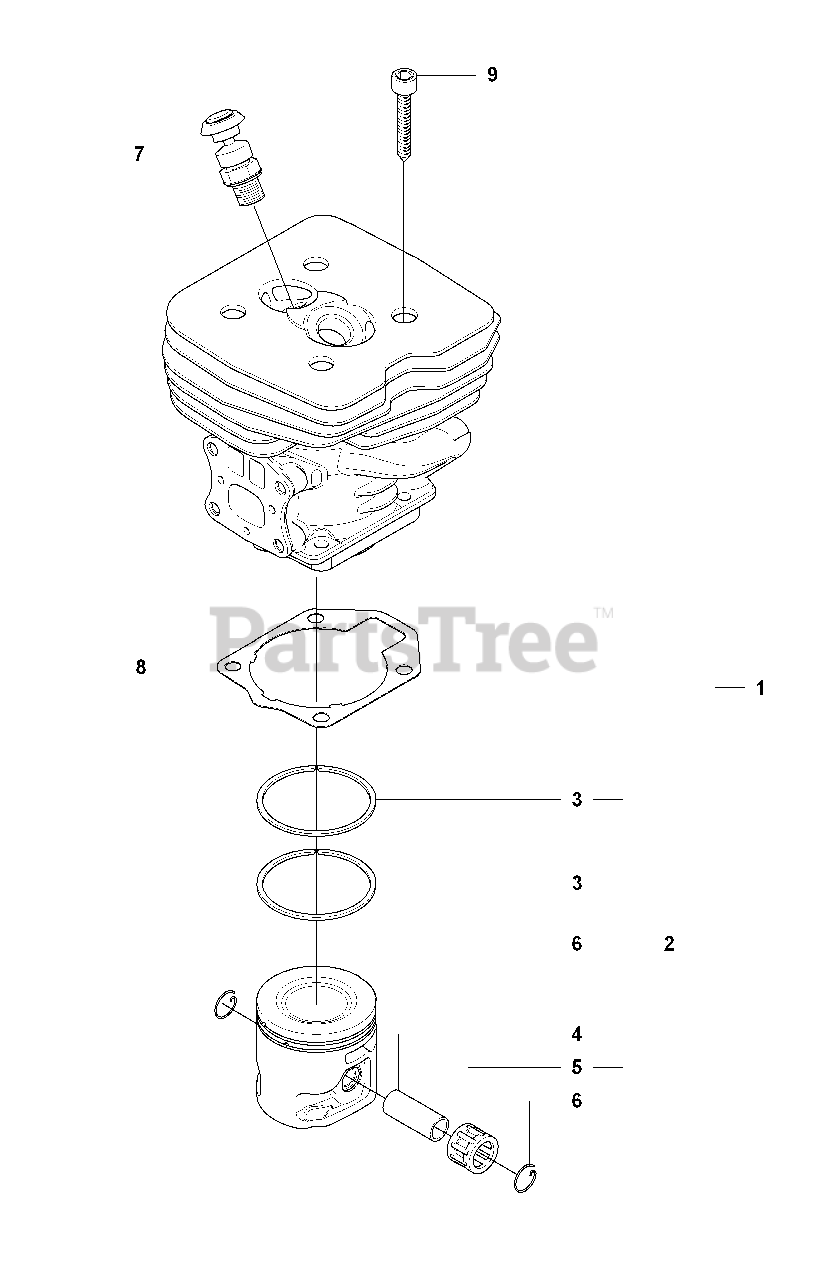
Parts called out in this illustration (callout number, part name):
3	PISTON RING
4	PISTON PIN
5	SUPPORT BUSHING
6	CIRCLIP
7	DECOMPRESSION VALVE
9	SCREW MC6S 5X25
